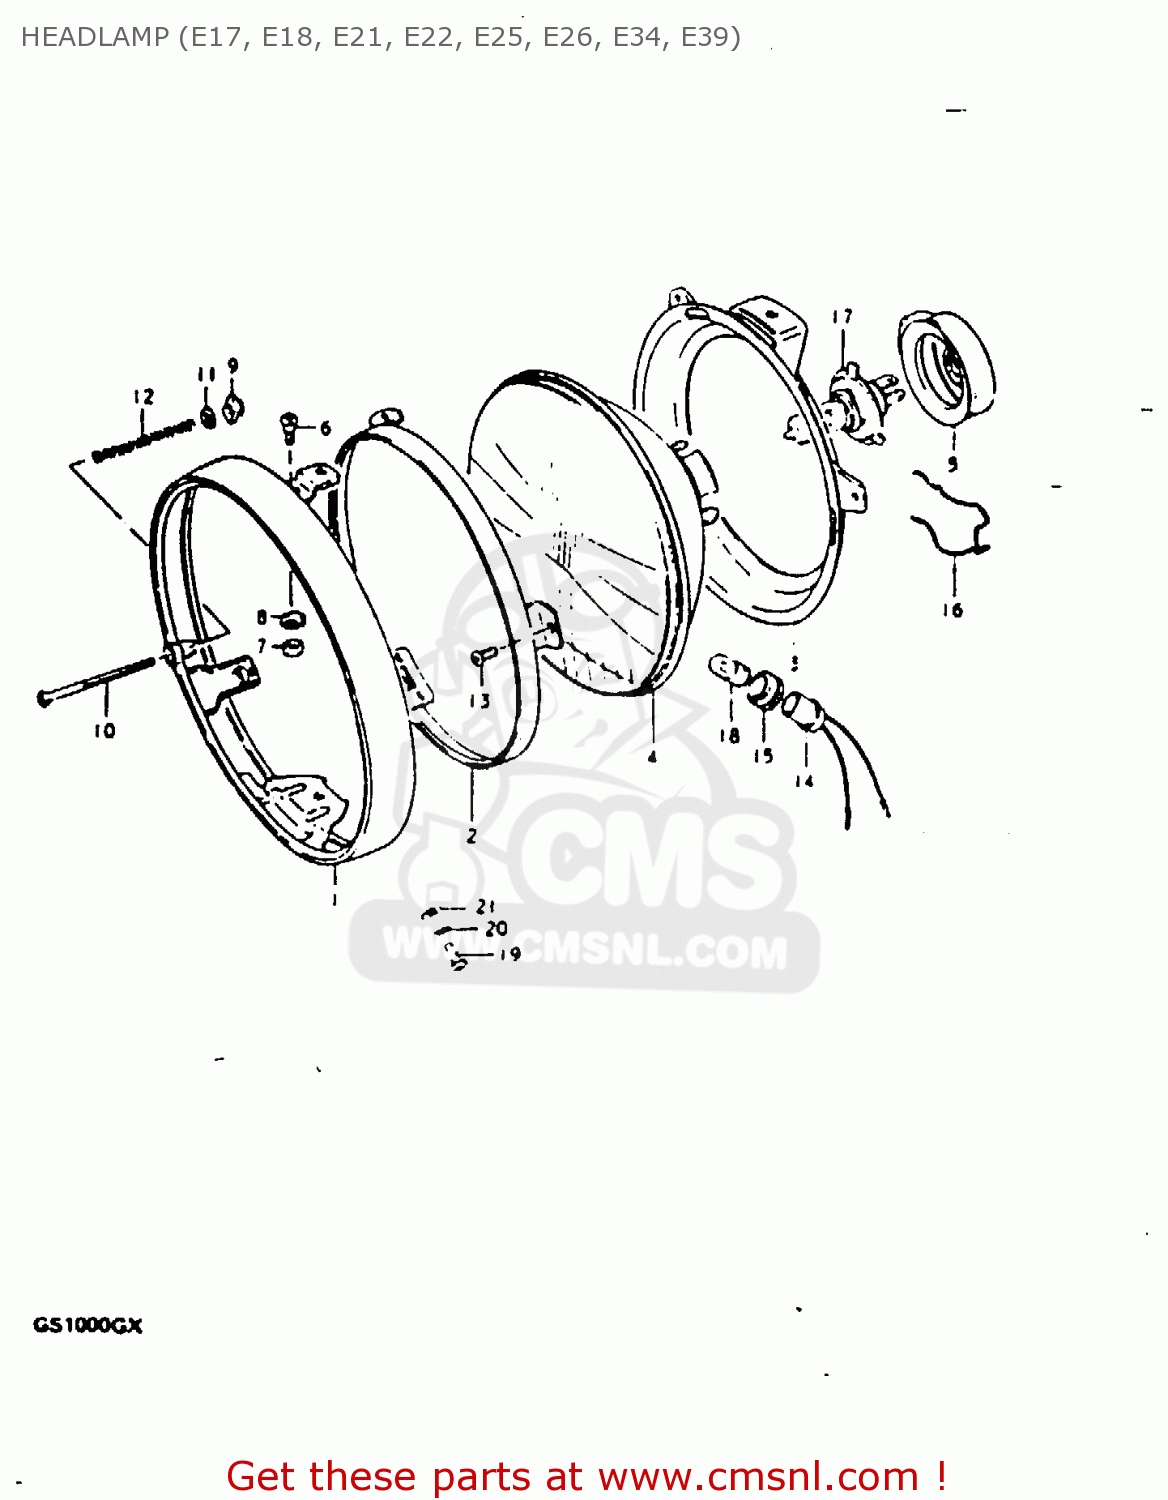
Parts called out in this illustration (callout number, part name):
1	RIM
2	RETAINER
3	RING,HEADLAMP UNIT
4	UNIT,HEAD LAMP
5	COVER,HEADLAMP SOCKET
6	SCREW
7	NUT,ADJUSTING
8	SPACER
9	NUT
10	SCREW,HEADLAMP ADJUST
11	WASHER
12	SPRING,HEADLAMP ADJUST
13	SCREW
14	SOCKET
15	JOINT,RUBBER
16	CLAMP,HEADLAMP SOCKET
17	BULB(12V60/55W,H4)
18	BULB(12V4W)
19	SCREW
20	WASHER,LOCK
21	WASHER
